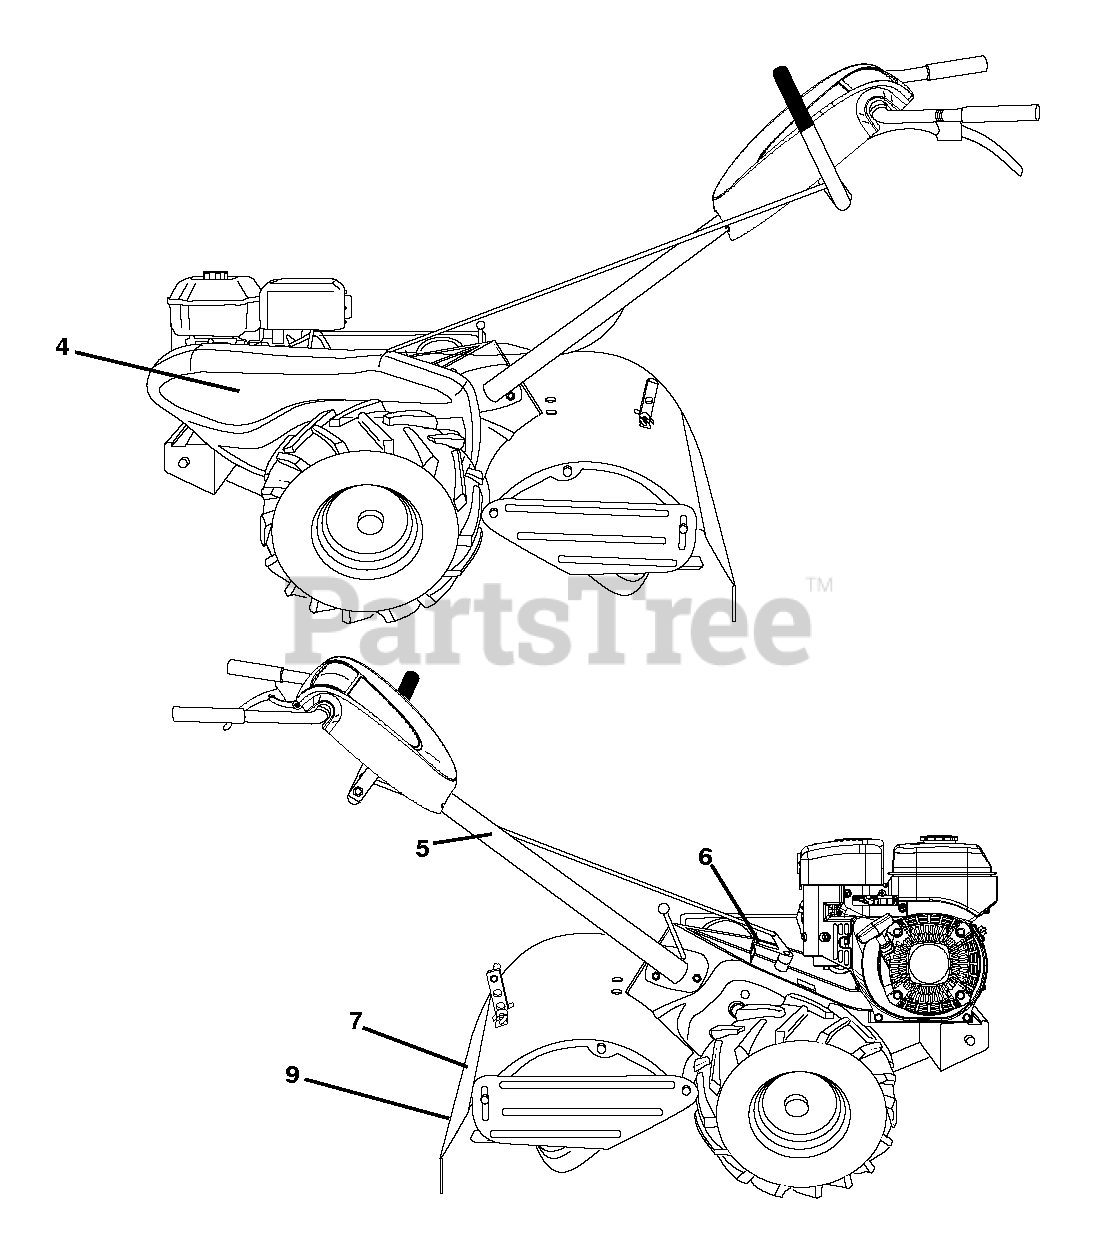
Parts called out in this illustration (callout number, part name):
5	DECAL TI
6	DECAL.SHIFT.INDICATOR.TILLER
7	DECAL WARNING
